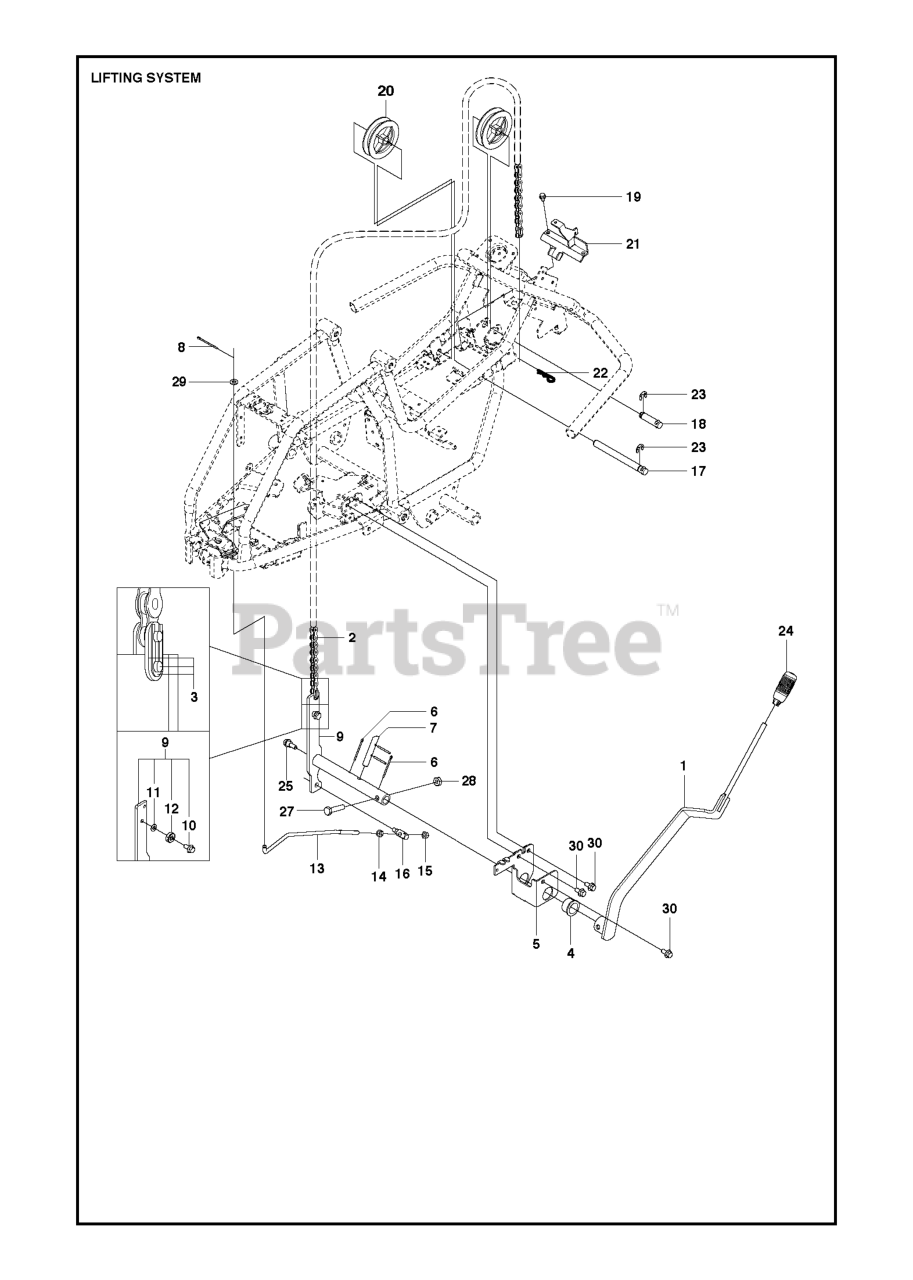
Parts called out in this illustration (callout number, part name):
1	LEVER ASSY
4	BEARING FLANGE
5	BRACKET ASSY
6	COTTER PIN
9	LEVER ASSY
10	BOLT FLANGE - M8X16
11	WASHER - 15X7.3X1.6
12	BALL BEARING
14	NUT
15	LOCKNUT M8
24	GEAR STICK KNOB
27	REPL BY 725 25 00-71
28	NUT
29	WASHER BRB 8.4X17
